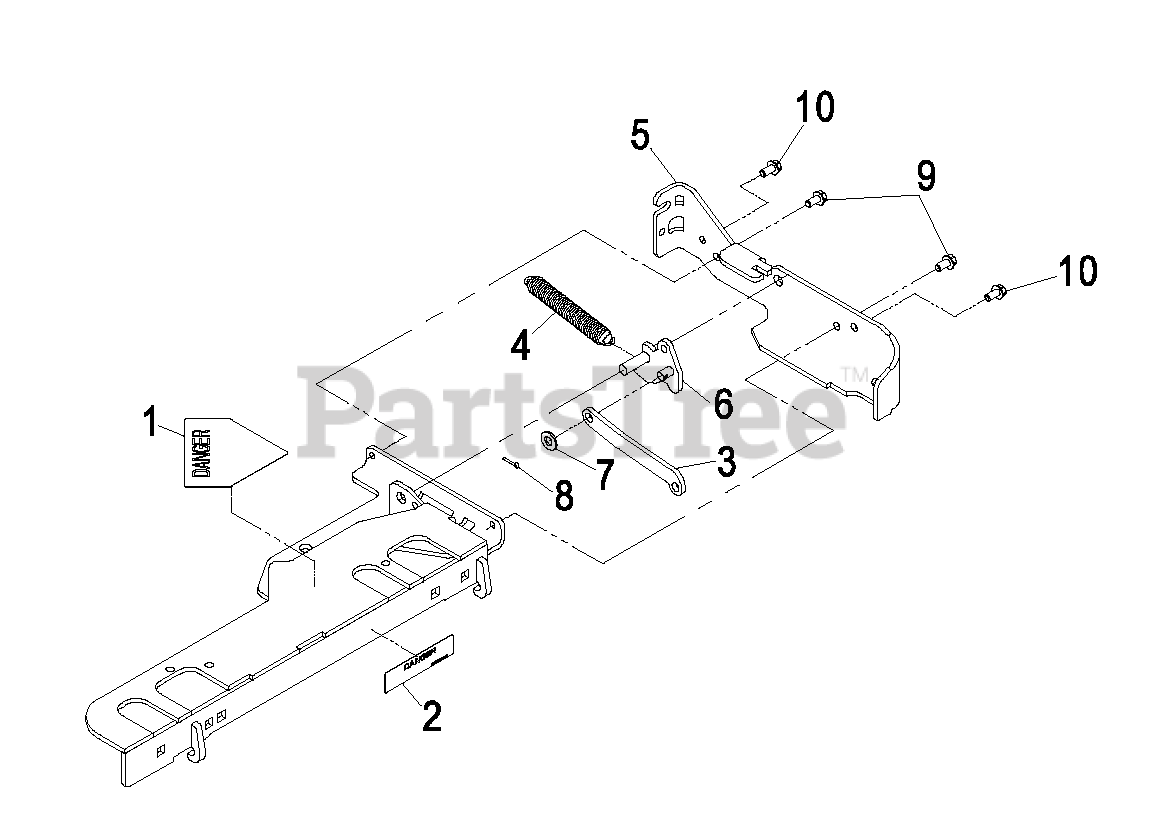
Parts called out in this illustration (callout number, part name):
1	DECAL-DANGER
2	DECAL-COVER, MISSING
3	LINK,GATE OCDC
4	SPRING,EXTENSION .50 X 4.
5	BRACKET,LINK PIVOT
6	WLD,GATE CRANK
7	WASHER-PLAIN
8	PIN-COTTER
9	SCREW-HWH
